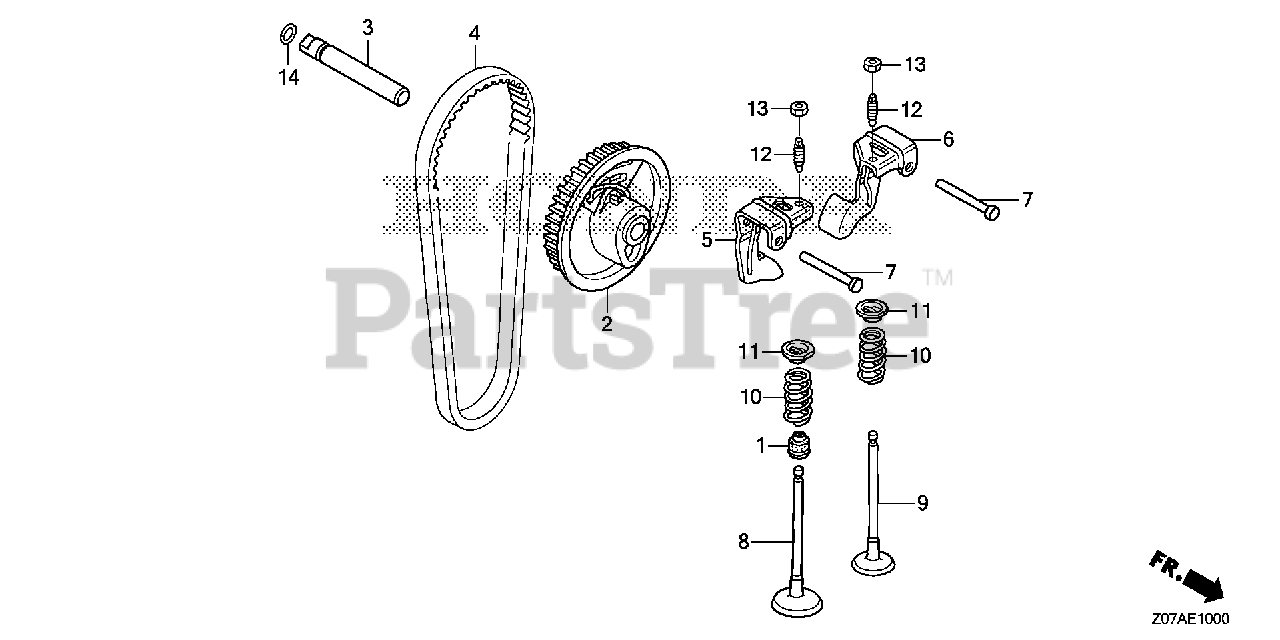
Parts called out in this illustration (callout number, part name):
1	SEAL, VALVE STEM
2	PULLEY, CAMSHAFT
3	SHAFT, CAM PULLEY
4	BELT, TIMING (61YU7 G-200)
5	ARM, IN. VALVE ROCKER
6	ARM, EX. VALVE ROCKER
7	SHAFT, ROCKER ARM
8	VALVE, IN.
9	VALVE, EX.
10	SPRING, VALVE
11	RETAINER, VALVE SPRING
12	SCREW, TAPPET ADJUSTING
13	NUT, TAPPET ADJUSTING
14	O-RING (6.8X1.9) (ARAI)
